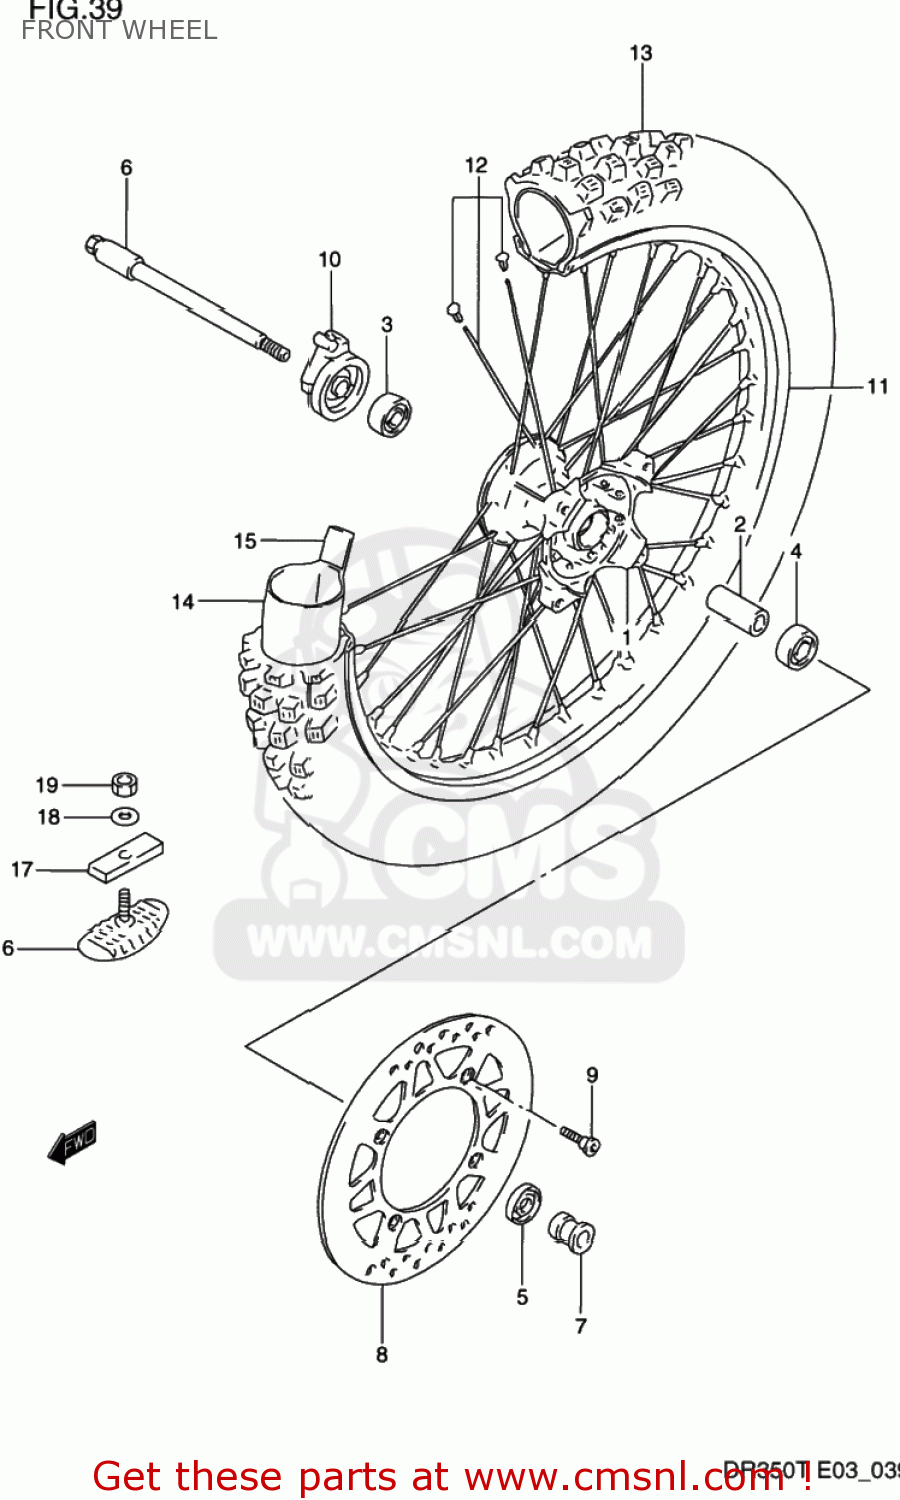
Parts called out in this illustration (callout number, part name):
1	HUB,FR WHEEL
2	SPACER,FR HUB BEARING
3	BEARING
4	BEARING
5	SEAL,OIL(22X35X5)
6	AXLE,FR
7	SPACER,FR AXLE,L
8	DISC,FR BRAKE
9	BOLT,BRAKE DISC
10	BOX ASSY,SPEEDOMETER GEAR
11	RIM,FRONT WHEEL (1.60X2
12	SPOKE SET,FR WHEEL
13	TIRE COMP,FRONT 80/100-21
14	TUBE
15	PROTECTOR,WHEEL INNER
16	STOPPER,BEAD
17	CUSHION,BEAD STOPPER
18	WASHER
19	NUT
